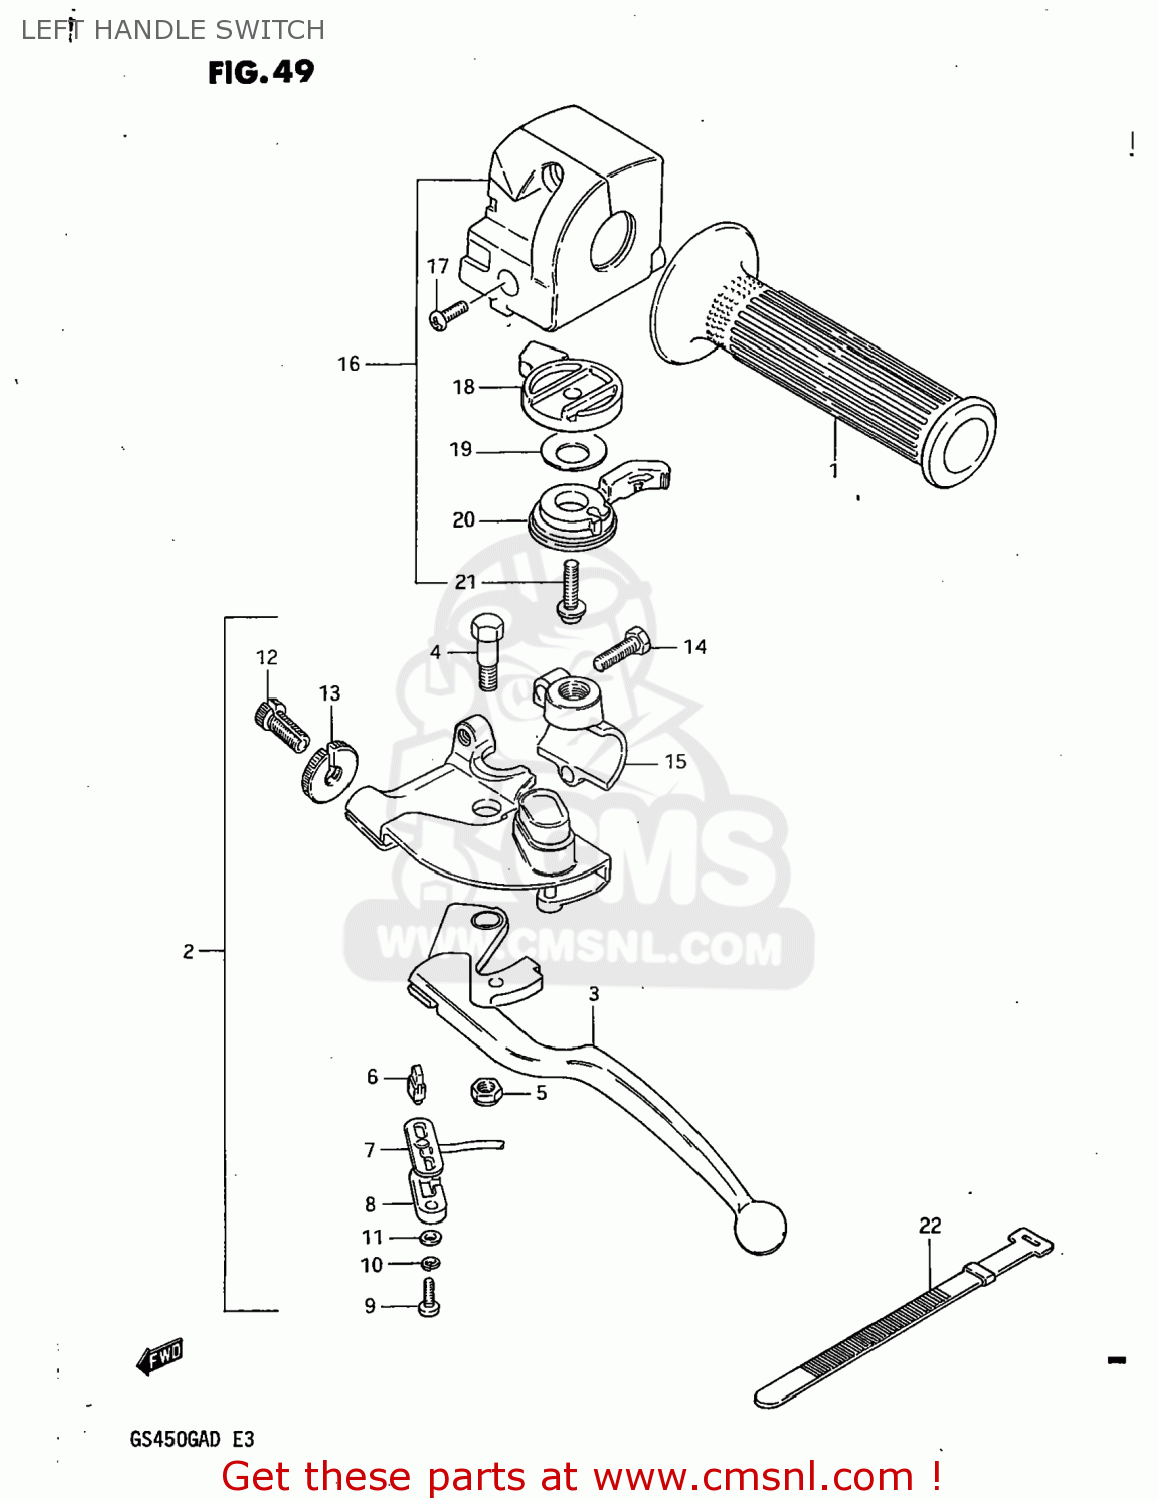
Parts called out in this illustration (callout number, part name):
1	GRIP,LEFT
2	LEVER ASSEMBLY
3	LEVER,PARKING
4	BOLT,LEVER
5	NUT 6MM
6	CONTACT,SWITCH
7	COVER,KNUCKLE,LEFT
8	COVER,FR BK TERMINAL BASE
9	SCREW
10	LOCK WASHER
11	WASHER
12	ADJUSTER,CABLE
13	NUT,CABLE ADJUSTER LOCK
14	BOLT,CLUTCH LEVER HOLDER
15	HOLDER
16	SWITCH ASSEMBLY,HANDLE,LEFT
17	SCREW
18	BODY,STARTER LEVER
19	WASHER,ADJUSTER
20	LEVER,STARTER
21	SCREW,CHOKE LE
22	CLAMP(L:120)
